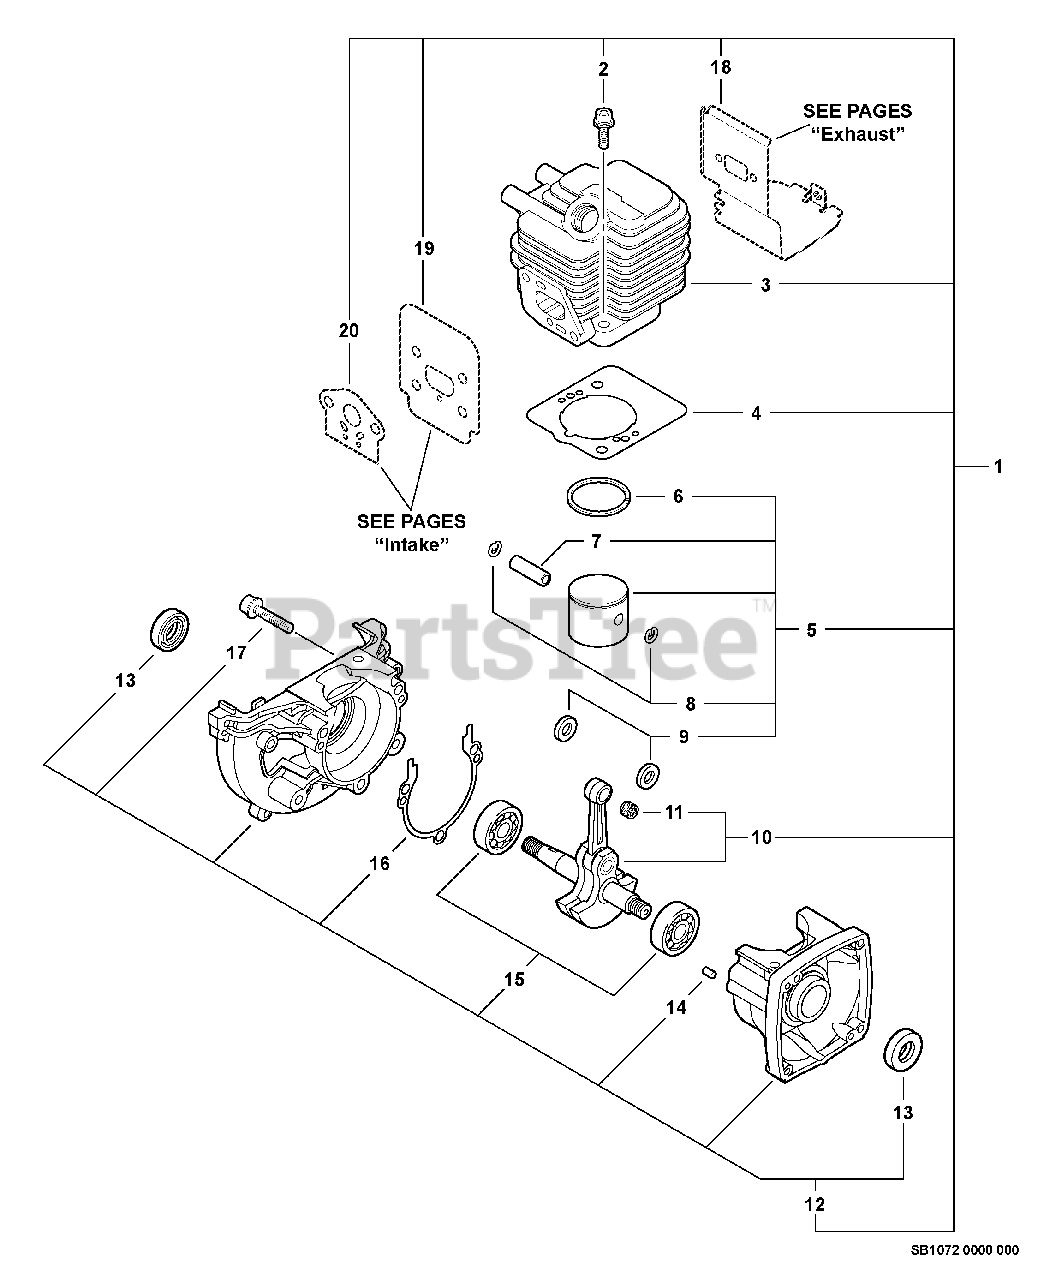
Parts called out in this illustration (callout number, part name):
1	SHORT BLOCK -- SB1072
2	SCREW - 5X22
3	CYLINDER
4	GASKET, CYLINDER
5	PISTON KIT
6	RING, PISTON
7	PIN, PISTON
8	RING, RETAINING
9	SPACER, PISTON
10	CRANKSHAFT ASSY
11	BEARING, NEEDLE - 8
12	CRANKCASE KIT
13	SEAL, OIL
14	PIN - LOCATING
15	BEARING, BALL - 6201
16	GASKET, CRANKCASE
17	SCREW - 5X28
18	SHIELD, EXHAUST
19	SHIELD, INTAKE
20	GASKET, INTAKE
